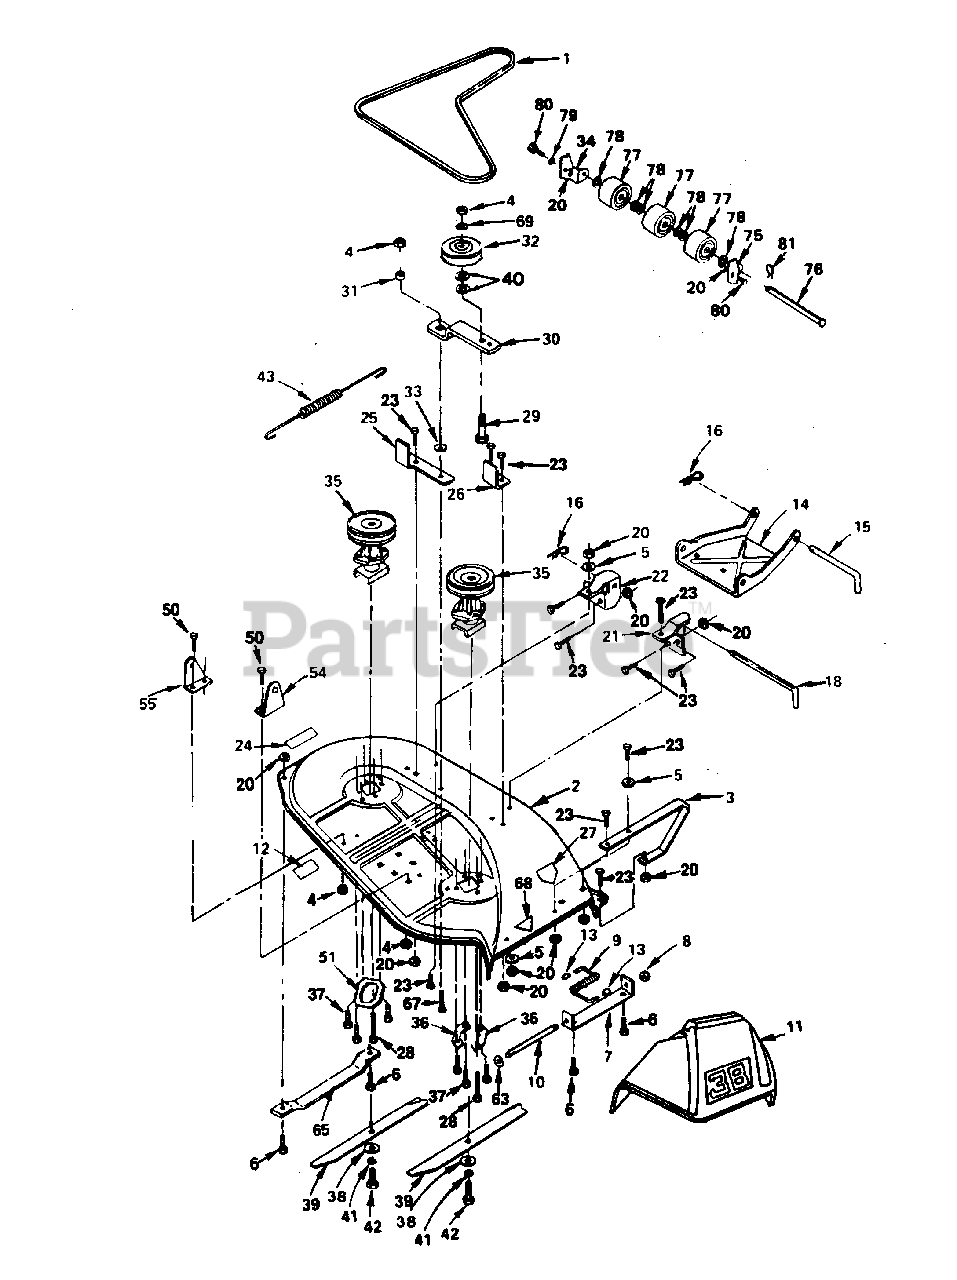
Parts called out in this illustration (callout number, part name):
1	V-Belt (AYP part number)
2	Housing (AYP part number)
3	R.H. Runner (AYP part number)
4	Locknut
5	Washer (AYP part number)
6	Carriage Bolt (AYP part number)
7	Deflector Bolt (AYP part number)
8	Push Nut (AYP part number)
9	Deflector Spring (AYP part number)
10	Hinge Rod (AYP part number)
11	Shield Deflector (AYP part number)
12	V-Belt Schematic Decal (AYP part number)
13	Sleeve Cap (AYP part number)
14	Parallel Link (AYP part number)
15	Front Hinge Pin (AYP part number)
16	Retainer Spring (AYP part number)
18	Rear Hinge Pin (AYP part number)
20	Locknut
21	R.H. Lift Bracket (AYP part number)
22	L.H. Lift Bracket (AYP part number)
23	Carriage Bolt 5/16-18 x 3/4
24	Caution Instruction Decal (AYP part number)
25	Arm Support (AYP part number)
26	Front Deck Stop (AYP part number)
28	Washer Hd. Hex Screw (AYP part number)
29	Bolt 3/8-16 x 2 (AYP part number)
30	Idler Arm (AYP part number)
31	Spacer (AYP part number)
32	Idler Pulley (AYP part number)
33	Wear Washer (AYP part number)
34	L.H. Nose Roller Bracket (AYP part number)
35	Mandrel Assembly (AYP part number)
36	Mandrel Support Plate (AYP part number)
37	Washer Hd. Hex Screw (AYP part number)
38	Washer (AYP part number)
39	Blade 38"
40	Washer (AYP part number)
41	Washer (AYP part number)
42	Hex Bolt 3/8-24 x 1-1/2 Gr.5 (AYP part number)
43	Extension Spring (AYP part number)
50	Carriage Bolt 3/8-16 x 3/4 (AYP part number)
51	Support Plate (AYP part number)
54	R.H. Rear Bracket Suspension (AYP part number)
55	L.H. Rear Bracket Suspension (AYP part number)
63	Washer (AYP part number)
65	L.H. Runner (AYP part number)
67	Carriage Bolt (AYP part number)
68	Warning Decal (AYP part number)
69	Washer (AYP part number)
75	R.H. Nose Roller Bracket
76	Pivot Pin (AYP part number)
77	Nose Roller (AYP part number)
78	Washer (AYP part number)
79	Washer (AYP part number)
80	Hex Bolt (AYP part number)
81	Cotter Pin (AYP part number)
